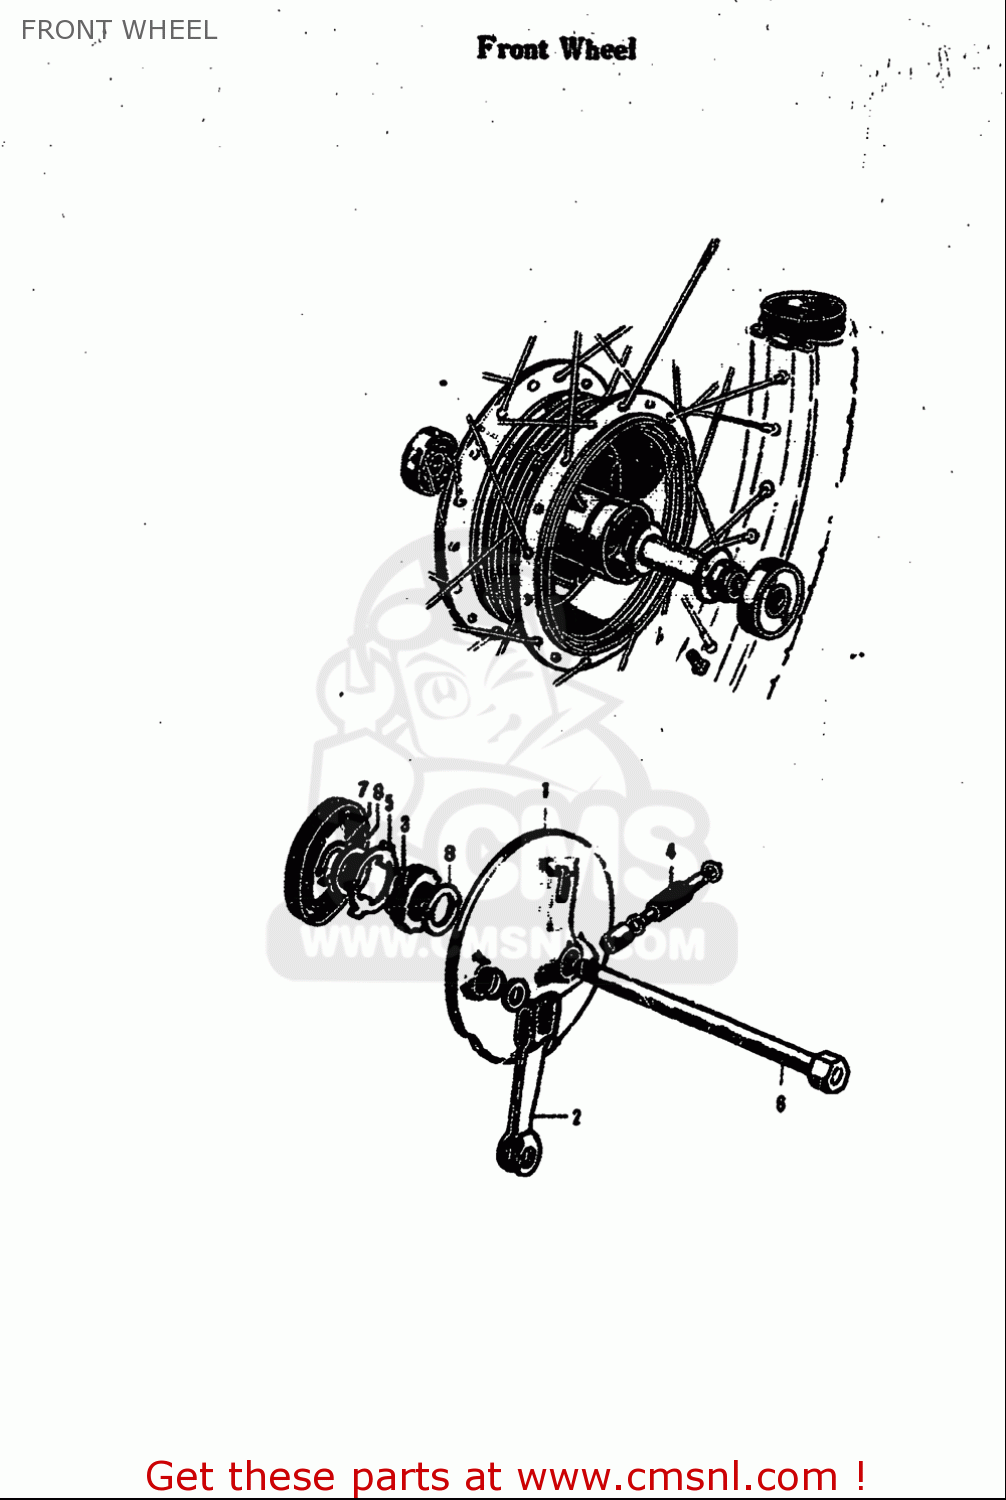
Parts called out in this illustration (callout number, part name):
2	LEVER,FR BRAKE CAM
3	GEAR,SPEEDOMETER(NT:24)
7	CIRCLIP
8	WASHER(16X22X1)
